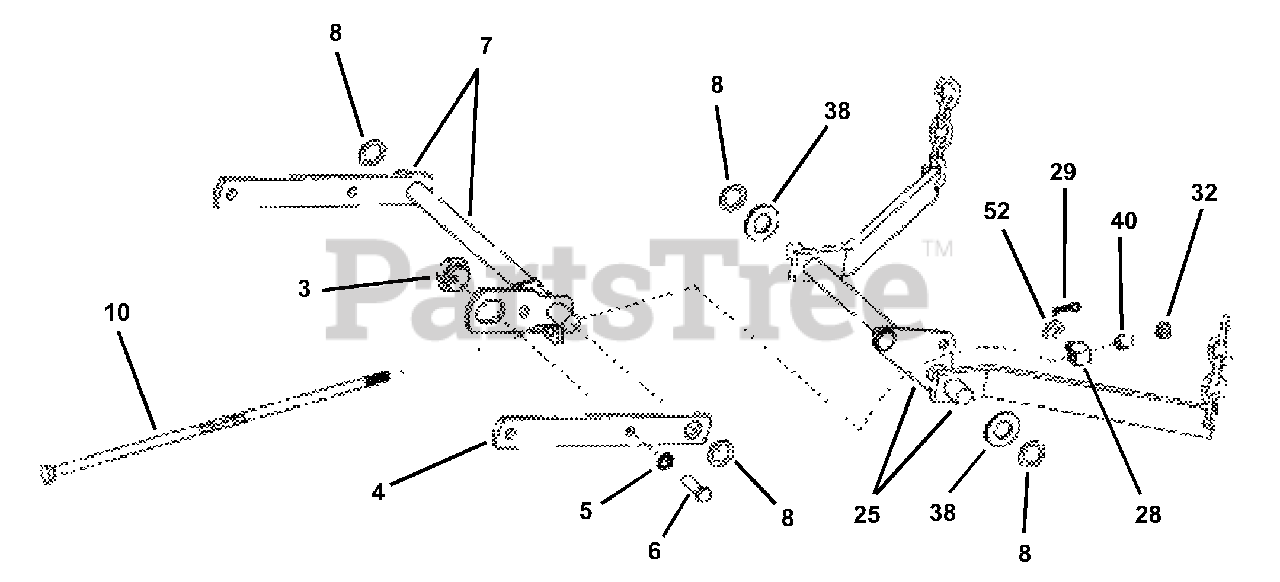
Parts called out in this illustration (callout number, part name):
3	ECCENTRIC, Leveling (3/8-24 thread)
4	LIFT ARM, Front
5	WASHER, 3/8" Internal Tooth Lk.
6	SCREW, 3/8-24 x 1-1/4" Hex Head Cap, Grade 5
7	LIFT ARM, Front (weldment)
8	WASHER, 3/4" x1-1/8" Flat
10	ROD, Cutter Deck Timing(3/8-16)
25	TIMING ARM, Rear (weldment)
28	SWIVEL, Brake Link
29	HAIR PIN, #13
32	NUT, 3/8-16 Hex Center Lock, Grade 5
38	WASHER, 3/4" x 1-1/2" Flat
40	SPACER, .391 I.D. x .520 O.D. x .531 Thick
52	WASHER, 3/8" Flat
